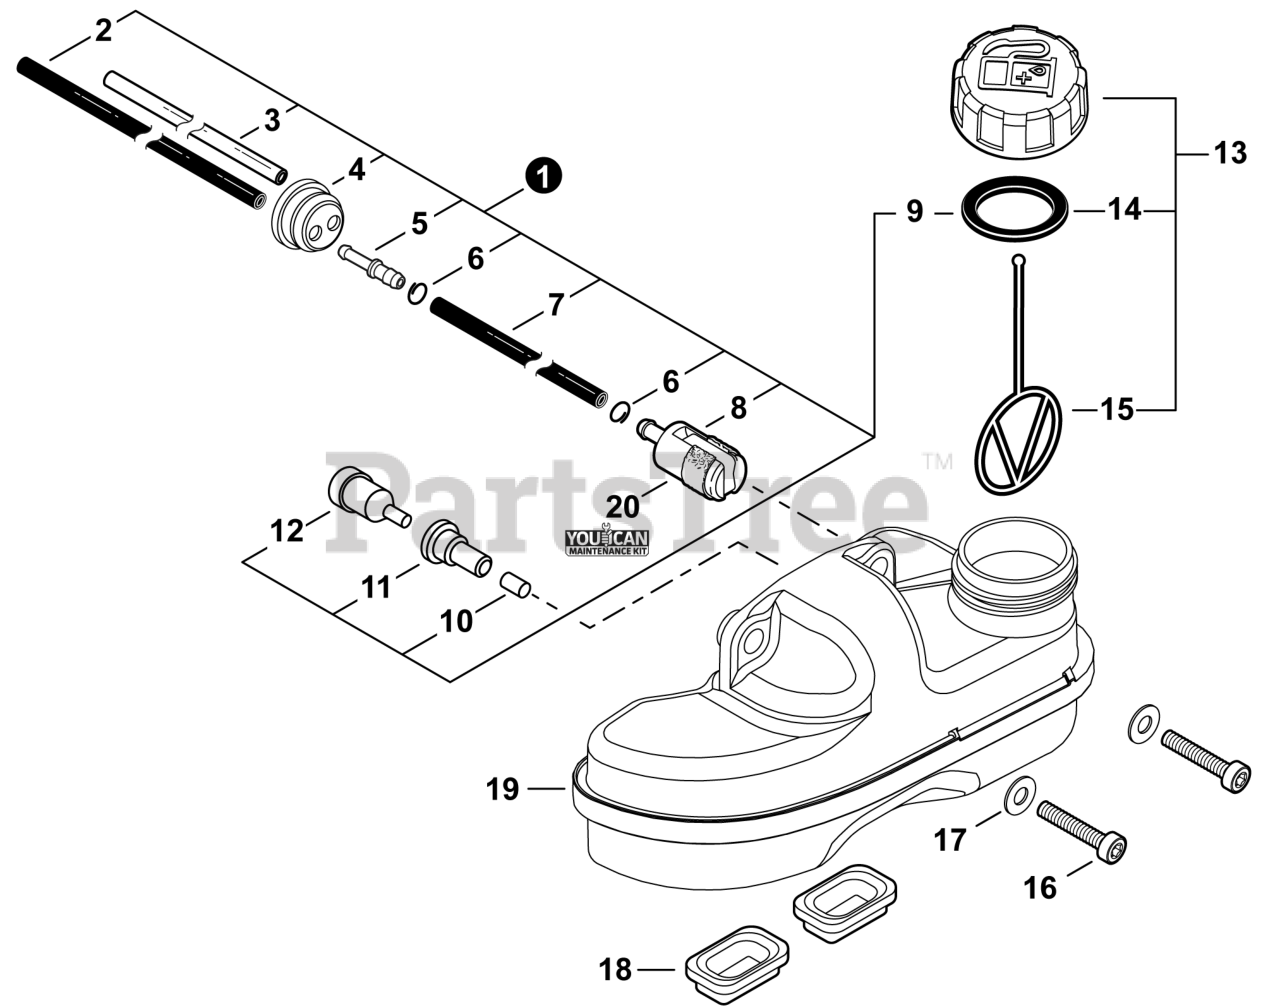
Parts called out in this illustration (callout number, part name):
1	FUEL SYSTEM KIT - YOUCANT
2	PIPE, FUEL 3x5.5x91 BLACK
3	PIPE, FUEL RETURN 3x6x90 MM CLEAR
4	GROMMET, FUEL
5	CONNECTOR, PIPE 5x3.5
7	PIPE, FUEL 3x5x115 BLACK
8	FILTER, FUEL
9	GASKET, FUEL CAP
10	FILTER, VENT
11	GROMMET, FUEL
12	VENT ASSY
13	CAP ASSY, FUEL
14	GASKET, FUEL CAP
15	CONNECTOR, CAP L= 60 MM
16	BOLT, TORX 5x20
17	WASHER 5.5x12x0.8
18	CUSHION
19	TANK, FUEL
20	TUNE-UP KIT - YOUCANT
